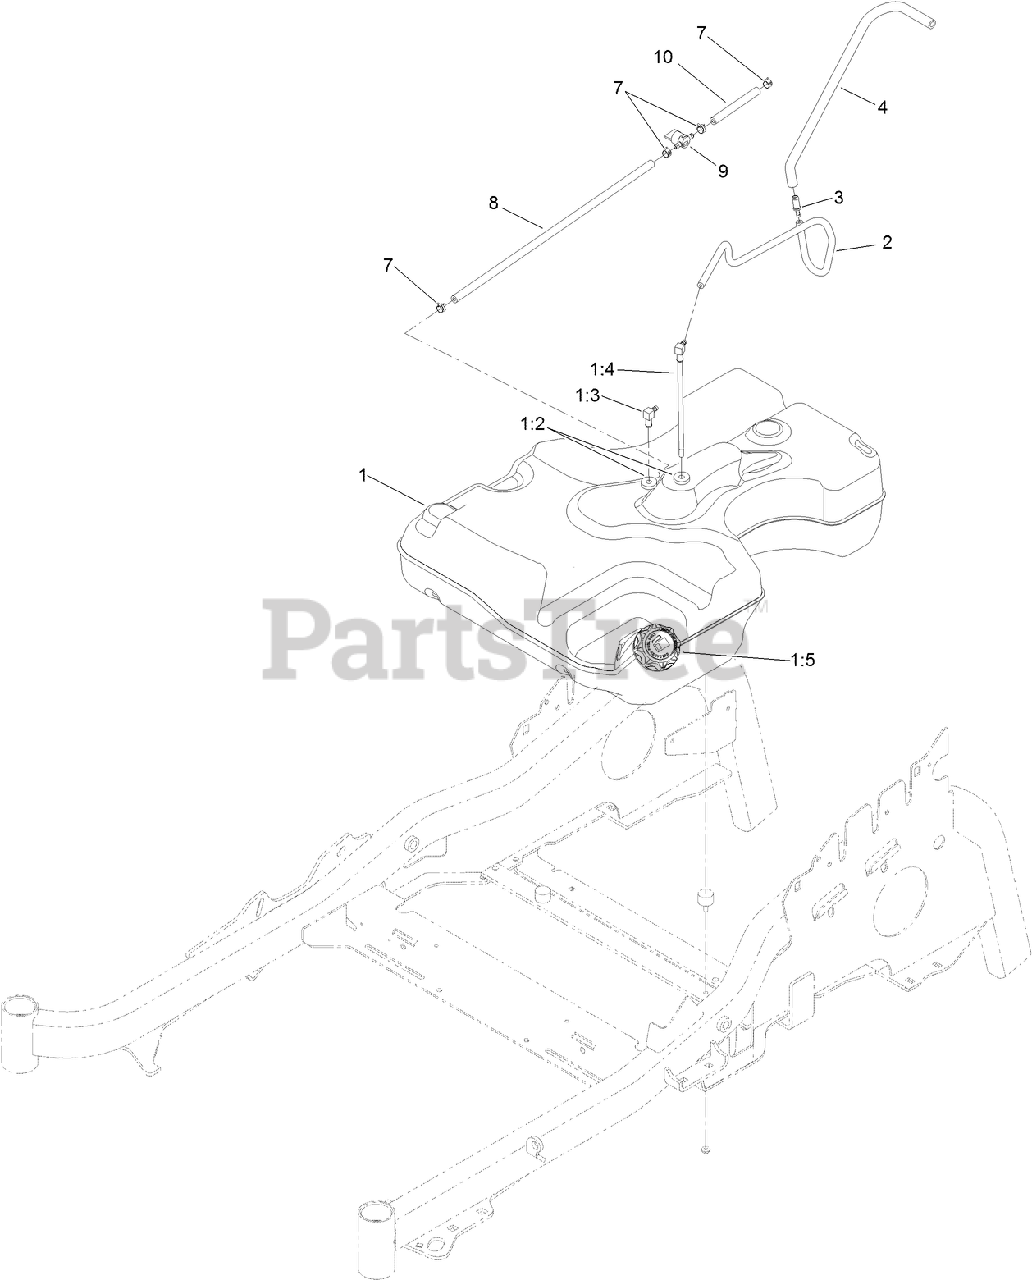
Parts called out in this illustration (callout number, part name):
1	FUEL TANK ASM
1:2	BUSHING
1:3	FITTING-90 ELBOW
1:4	FUEL LINE ASM
1:5	CAP-FUEL, RATCHETING
2	HOSE-FUEL
3	FITTING-STRAIGHT
4	HOSE-FUEL
7	CLAMP-HOSE
8	HOSE-FUEL
9	VALVE-FUEL
10	HOSE-FUEL
